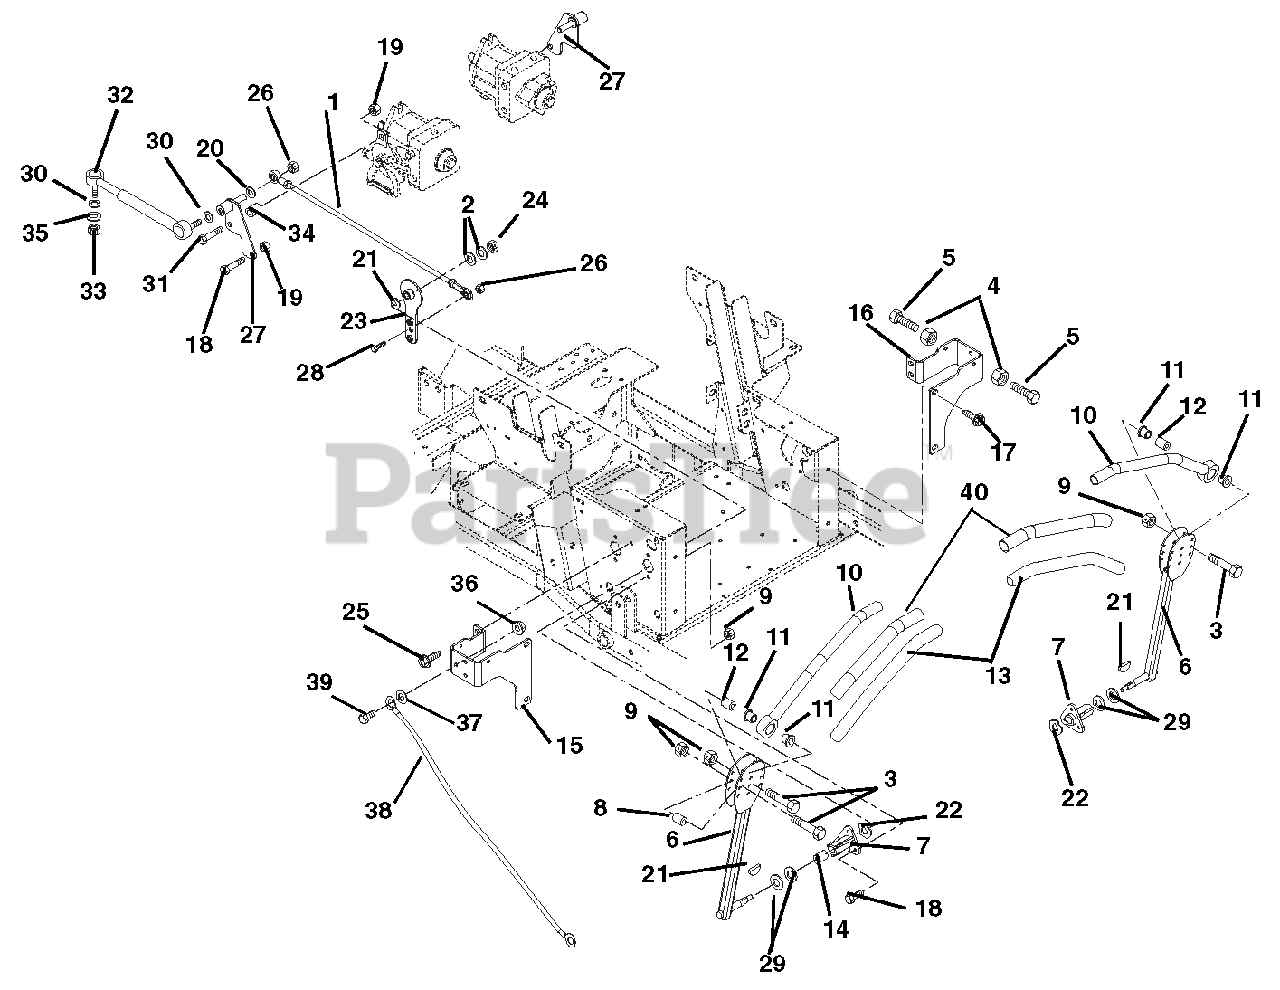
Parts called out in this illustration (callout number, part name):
1	ASSY,STEERING ROD .38RODX21.65
2	@WSHR-FL-STL.406X.812X.065 YWZ
3	@BLT-HEX .31-18X1.75 GR5 YWZC
4	NUT-HEX-JAM .375-16 YWZC
5	BLT-HEX .375-16X1.750 FTD YWZC
6	CONTROL ARM WELDMENT - BLACK
7	BUSHING, FLANGE
8	BSHG, ECCENTRIC .328X.750X.970
9	@NUT-LK-TOP-FLG .31-18 YWZC
10	HANDLE WLDMT LH
11	BSHG-FLG .762X1.48X.44 NYL
12	SPACER .328 X .76 X 1.01
13	GRIP, HANDLEBAR 1.00X1.38X11.3
14	BSHG .625X.750X.500
15	STOP, STEERING - RH
16	STOP, STEERING - LH
17	@SCR-TAP .38-16X.75 HWH TR YWZ
18	@BLT-HEX .31-18X.75 GR5 YWZC
19	@NUT-LK-TOP-FLG .31-18 YWZC
20	@WSHR-LK .38X.094 REG YWZC
21	KEY-WDRF .13X.63 HRD#5
22	WAVE WASHER .640X.875X.125FH
23	WMT, PIVOT ARM
24	@NUT-LK-TOP-FLG .38-16 YWZC
25	@SCR-TAP .38-16X.50 HWH TR YWZ
26	@NUT-LK-CTR-JAM .375-16 YWZC
27	WMT, RTN/DAMPER/ROD END
28	@BLT-HEX .38-16X1.25 GR5 YWZC
29	WSHR-FL-STL .630X1.005X.062 YZ
30	@WSHR-LK .31X.078 REG YWZC
31	@BLT-HEX .31-18X1.25 GR5 YWZC
32	DAMPENER
33	@NUT-LK-NYL M8-1.25 YWZC
34	SPACER .318X.430X.375
35	@WSHR-FL-STL.38X.875X.083 YWZC
36	@NUT-LK-TOP-FLG .25-20 YWZC
37	WSHR-FL-STL .265X.50X.087YWZC
38	CABLE, SEAT PROP.
39	@BLT-HEX .25-20X.75 GR5 YWZC
40	TUBE, .88ID X 1.00OD X 10.25
